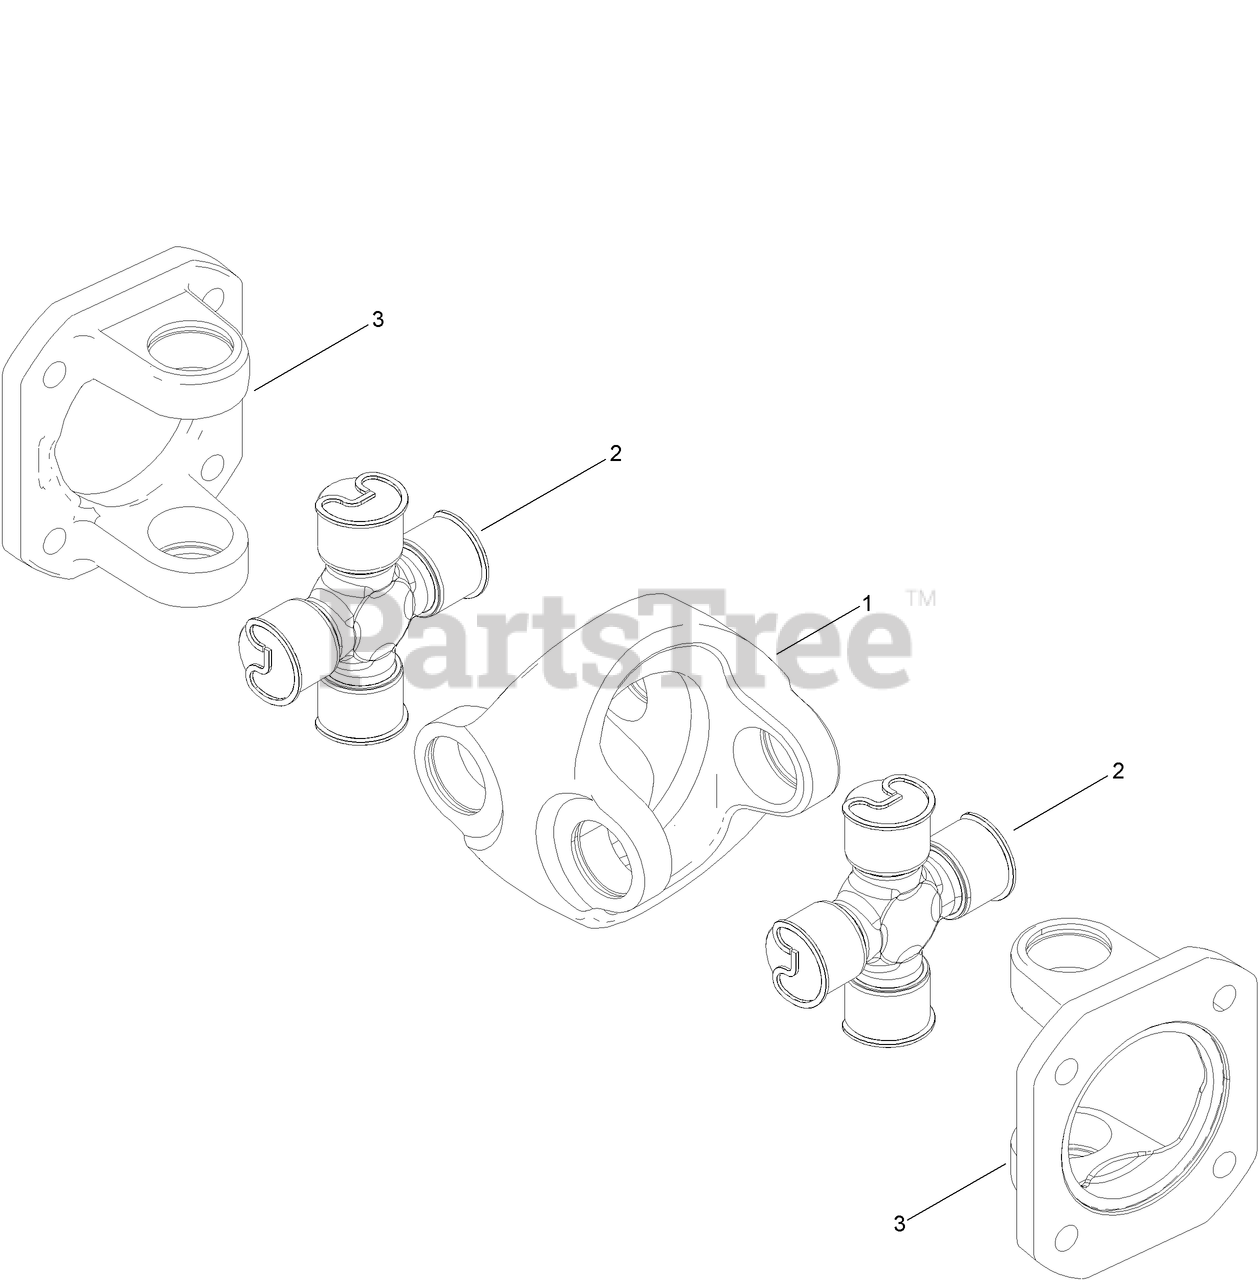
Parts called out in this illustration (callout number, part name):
1	CONNECTOR-CENTER
2	JOINT-Universal
3	FLANGE-Connection
